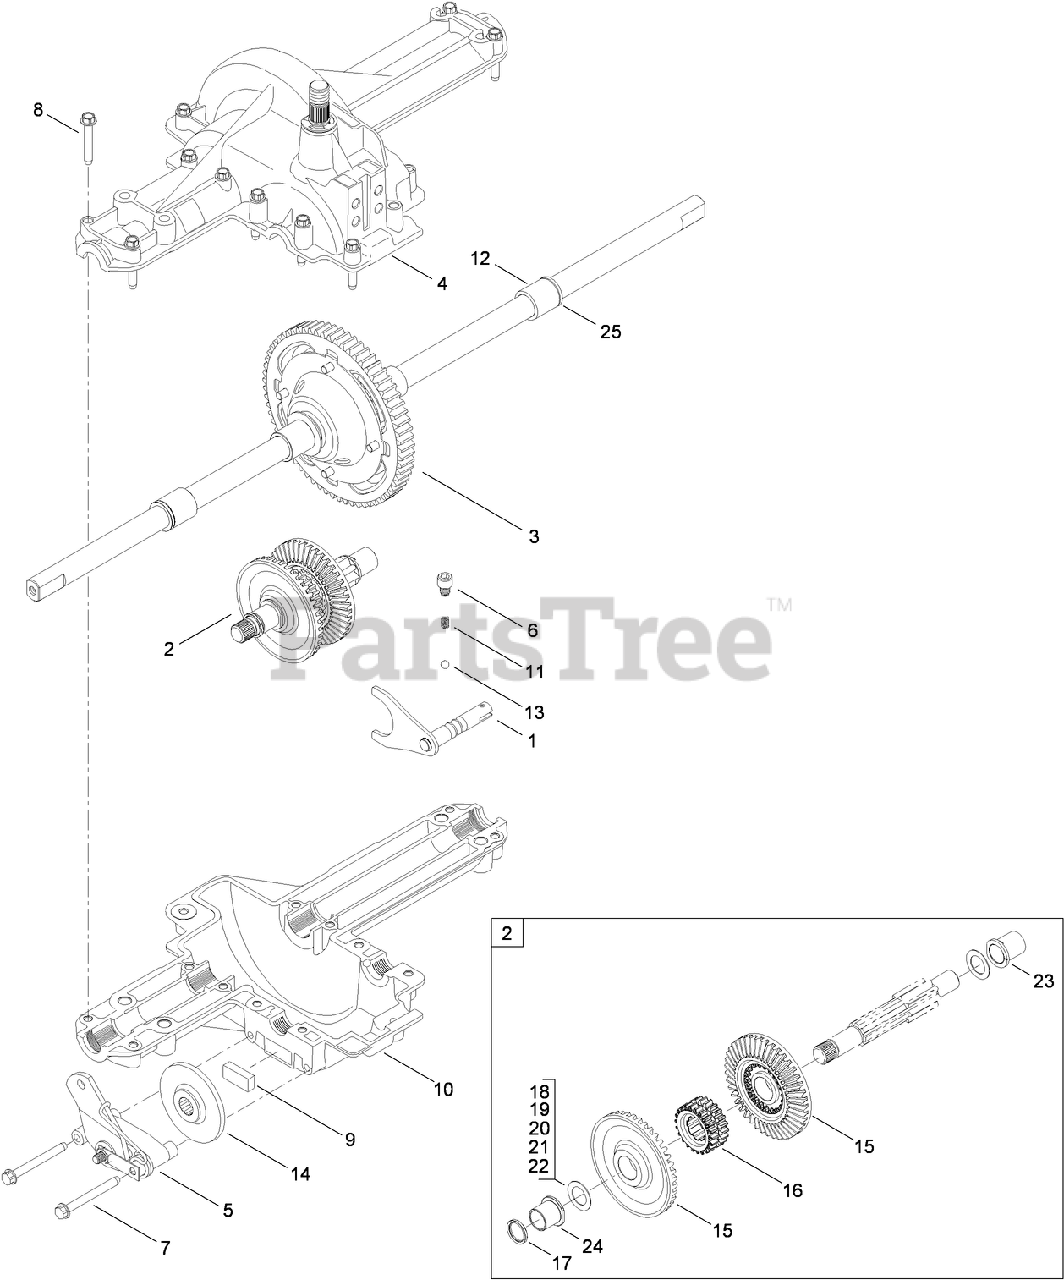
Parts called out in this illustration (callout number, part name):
1	SHIFT FORK ASM
2	DRIVE SHAFT ASM
3	DIFFERENTIAL ASM
4	UPPER HOUSING ASM
5	BRAKE ASM
6	SCREW-TAP
7	SCREW-HWH
8	SCREW-TAP
9	PUCK-BRAKE
10	HOUSING-LOWER
11	SPRING-DETENT
12	BEARING-SLEEVE
13	BALL-DETENT
14	DISC-BRAKE
15	GEAR-BEVEL, 42T (SPLINE)
16	COLLAR-CLUSTER
18	WASHER-FLAT
19	WASHER-FLAT
20	WASHER-FLAT
21	WASHER-THRUST
22	WASHER-THRUST
23	BEARING-FLANGE
24	BEARING-FLANGE
